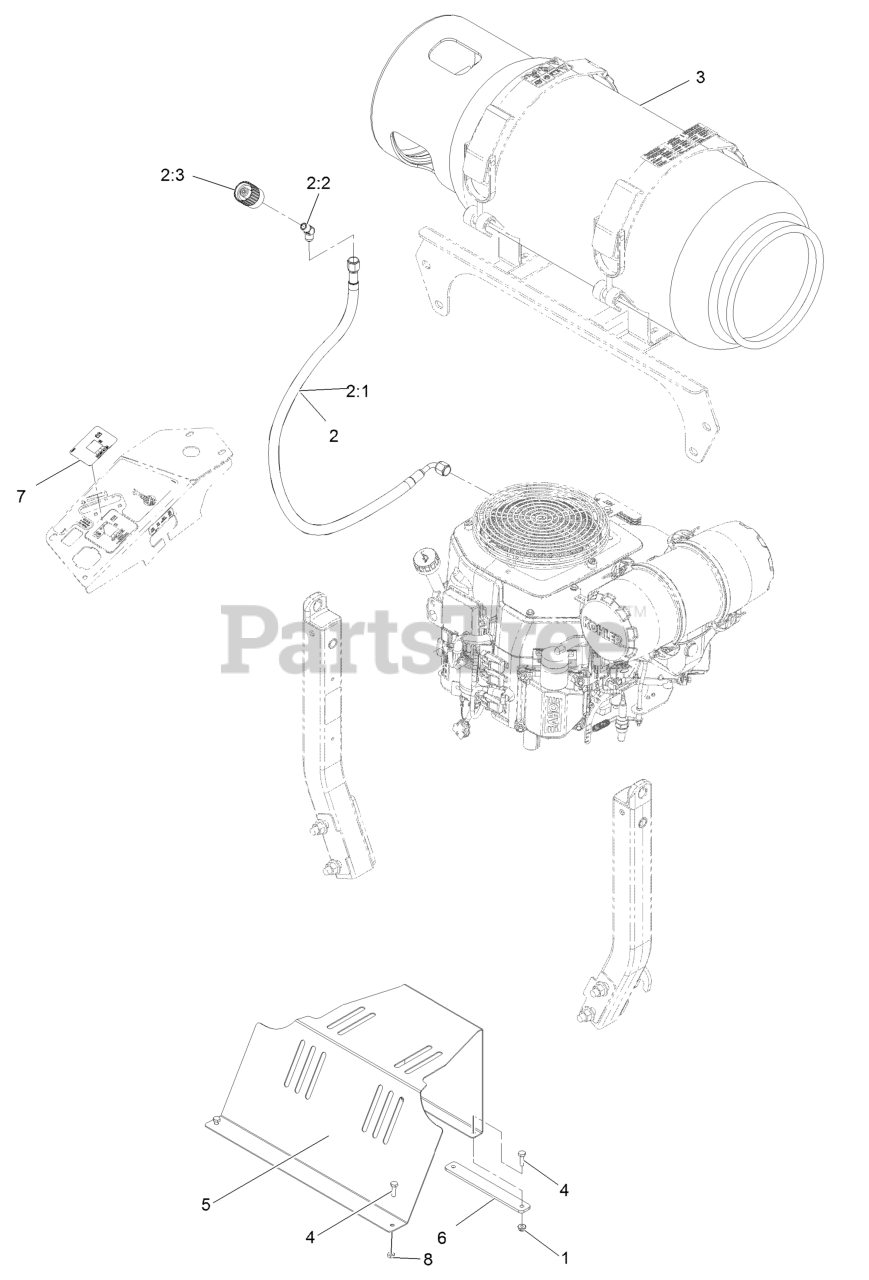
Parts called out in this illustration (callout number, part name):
2:1	LPG FUEL HOSE ASM
2:2	ELBOW-45 DEG
2:3	CONNECTOR-LPG TANK, LH TH
3	TANK-LPG
4	SCREW-HH
5	SHEILD-FAN
7	DECAL-METER, HOUR
8	NUT-JAM
